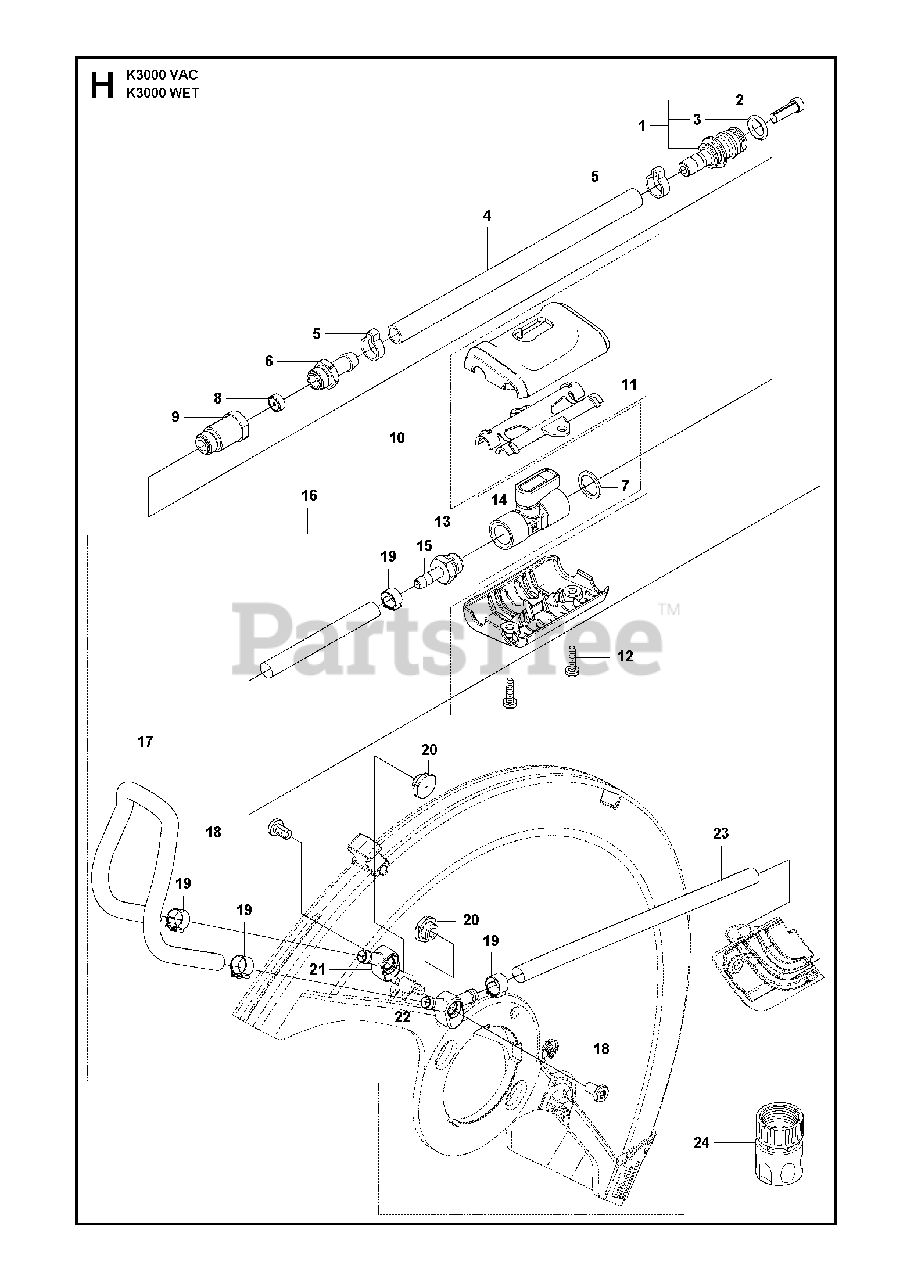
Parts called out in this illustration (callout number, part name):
1	NIPPLEIncl. 2 - 3
12	SCREW ITXSCT
13	VALVE KITIncl. 7, 14
16	HOSE KITIncl. 17 - 23
18	SCREW ITXSCM
23	HOSE720mm
